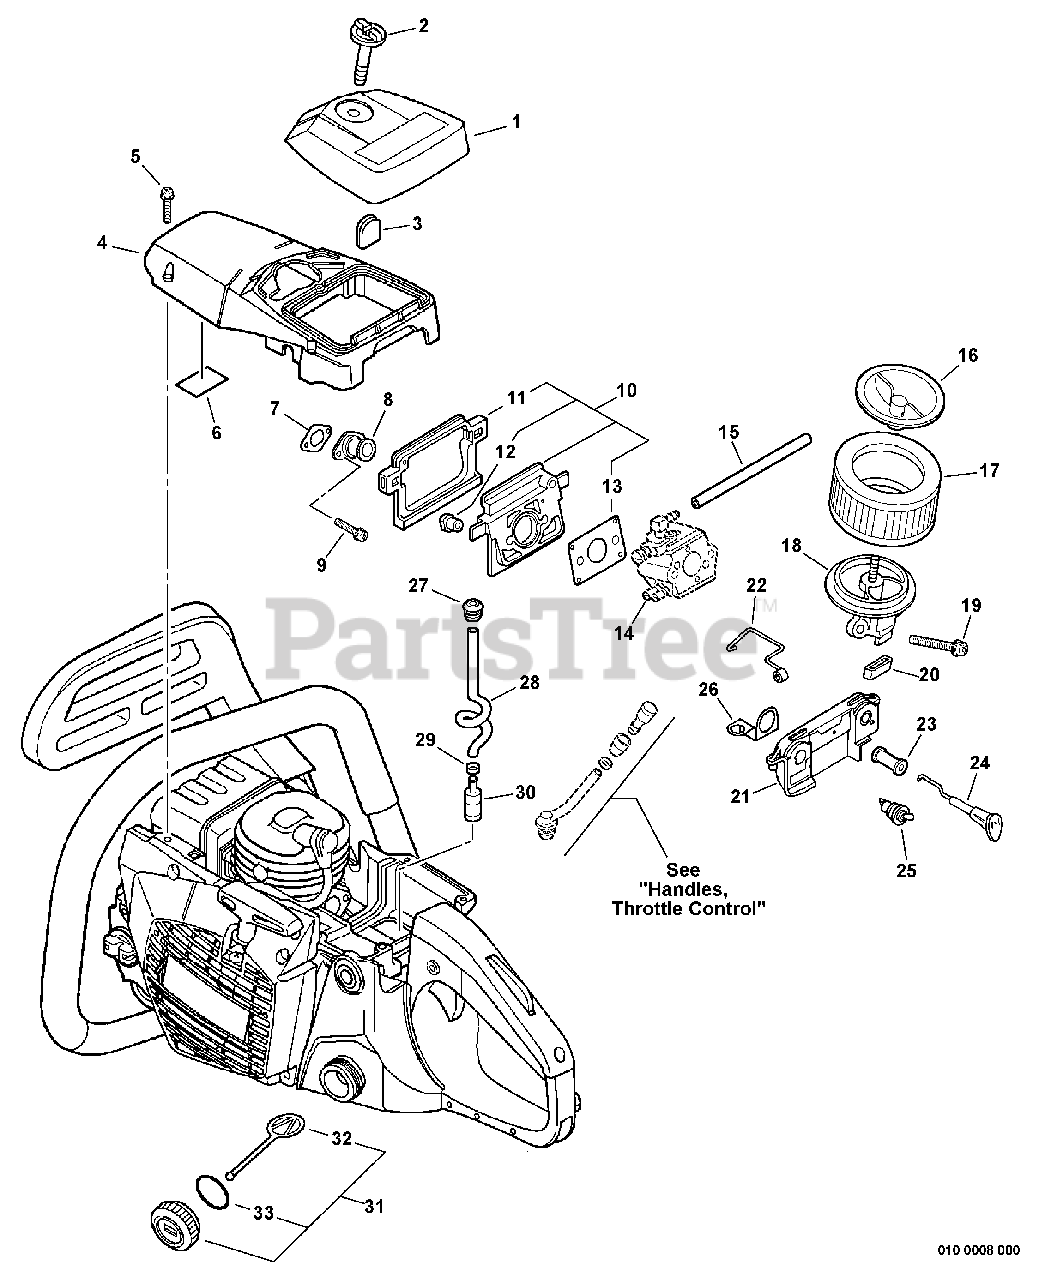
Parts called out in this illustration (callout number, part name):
1	AIR FILTER COVER ASSY - BLACK
2	THUMBSCREW
4	COVER, ENGINE
5	SCREW - 5
6	DEFLECTOR, HEAT
7	GASKET, INTAKE
8	ADAPTOR, INTAKE
9	SCREW - 5X12
10	INSULATOR KIT
11	CUSHION
13	GASKET, INTAKE
14	CARBURETOR
15	PIPE - IMPULSE
16	COVER, AIR FILTER
17	FILTER, AIR
18	ADAPTOR, INTAKE
19	SCREW - 5X50
21	BRACKET, SWITCH
22	ROD, THROTTLE
23	GROMMET
24	ROD, CHOKE
25	IGNITION SWITCH ASSY
26	TERMINAL - GROUND
28	PIPE, FUEL - SPIRAL
29	CLIP - 6.5
30	FILTER, FUEL
31	CAP ASSY - ORANGE
32	CONNECTOR, CAP
33	O-RING - 22
